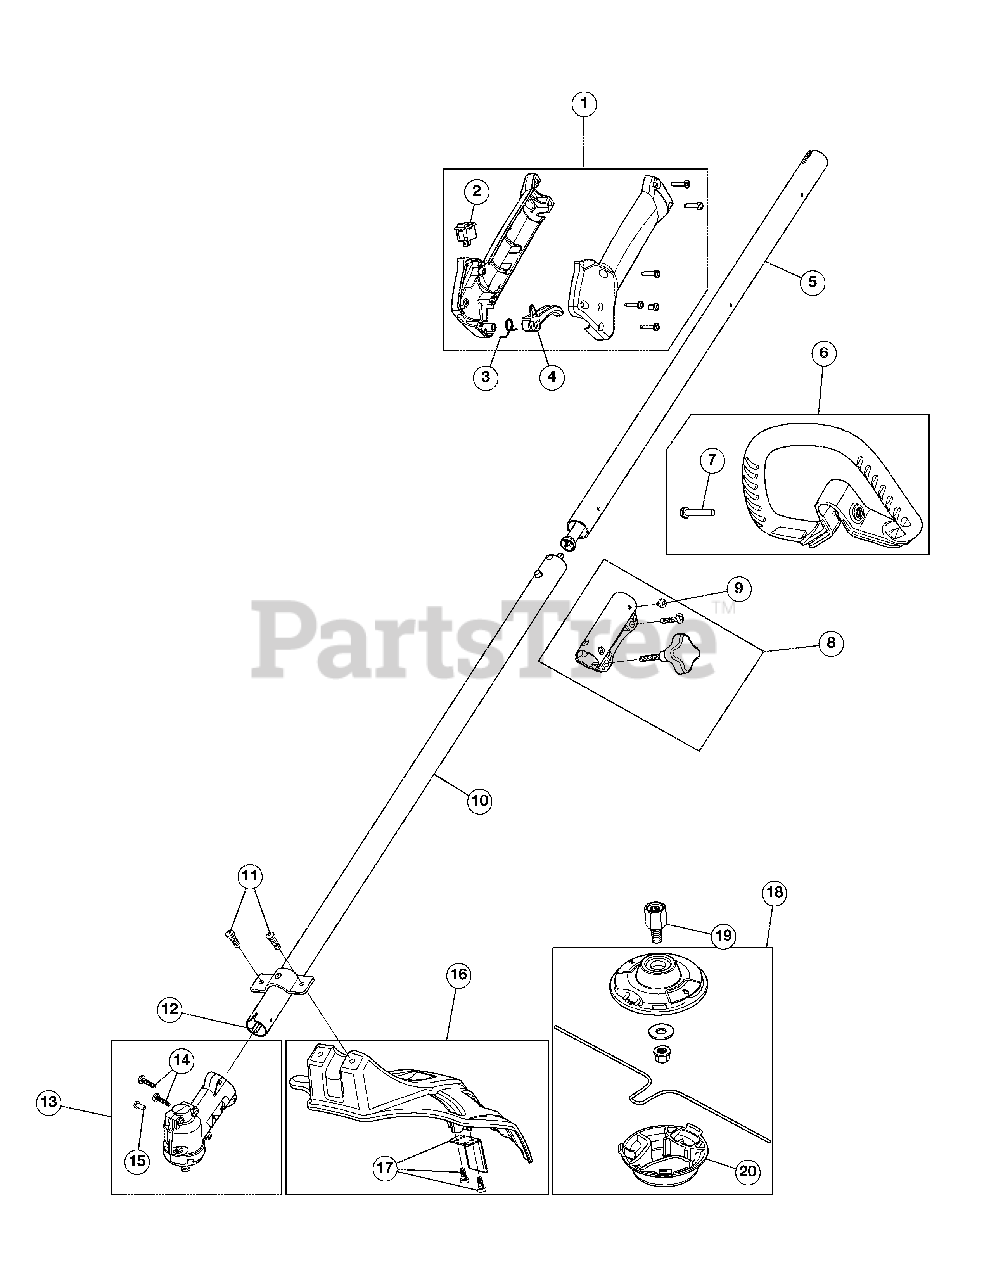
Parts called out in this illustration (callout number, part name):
1	Throttle Housing Assembly (Incl. 2 - 4)
2	Switch Assembly
3	Throttle Trigger Spring
4	Throttle Trigger
5	Upper Drive Shaft Assembly
6	D-Handle Assembly (Incl. 7)
8	Split Boom Coupler (Incl. 9)
9	Coupler Anti-Rotation Screw
10	Lower Drive Shaft Housing
11	Shield Mounting Screws
12	Lower Flexible Drive Shaft
13	Gearbox Assembly (Incl. 14 and 15)
14	Anti-Rotation Screw
15	Gearbox Mounting Hardware
16	Shield Assembly (Incl. 17)
17	Blade Assembly
18	Cutting Head Assembly (Incl. 20)
19	Shaft Extension
